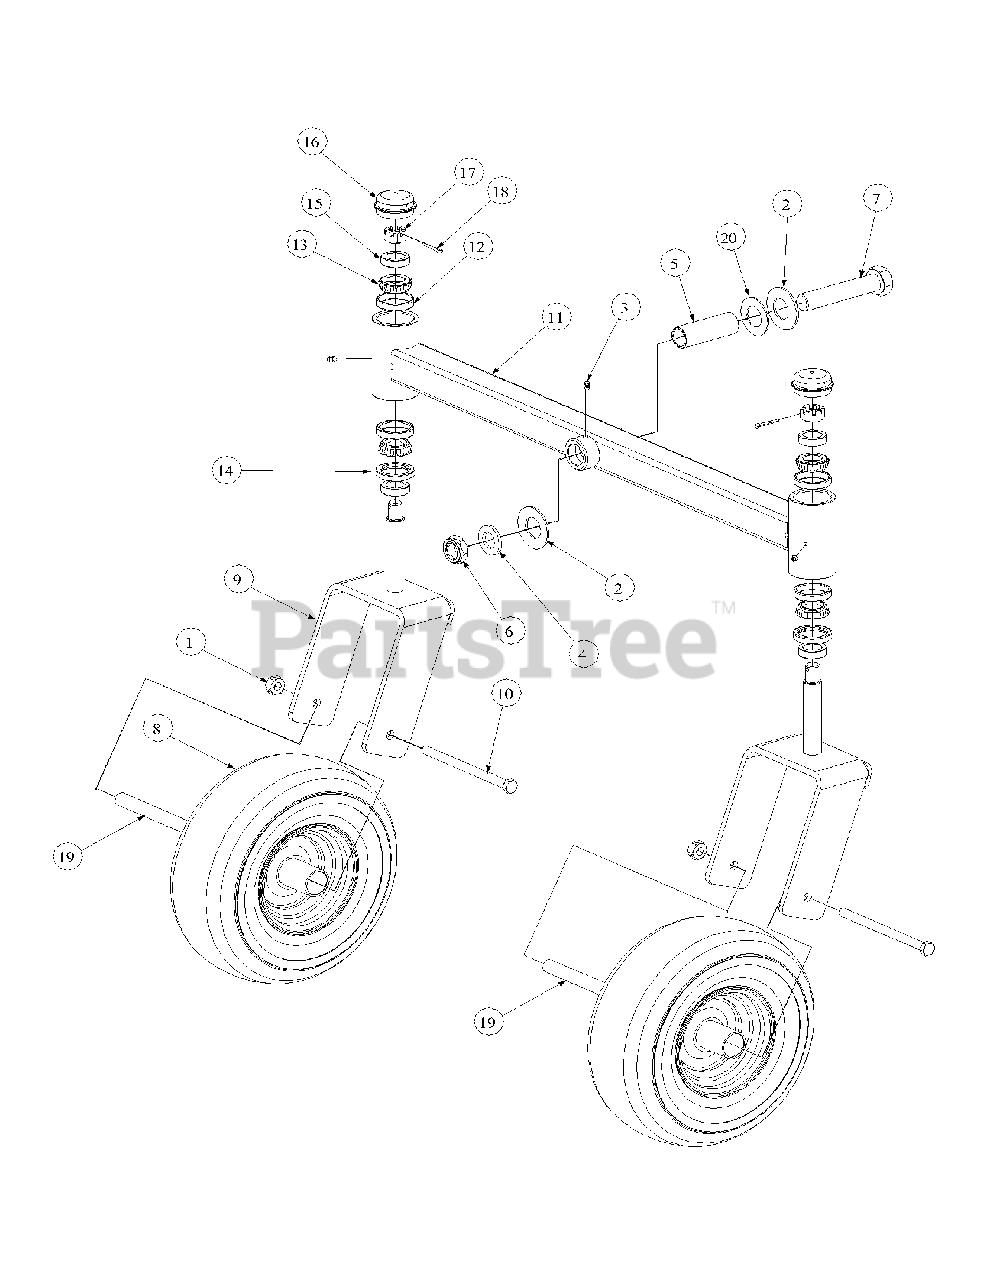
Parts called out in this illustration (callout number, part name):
1	Nut, 1/2-20, Center Lock
2	Bell Washer, 1.25 ID
3	Grease Fitting
4	Special Washer
5	Spacer, 1.005 ID x 1.25 OD x 3.6
6	Nut, Jam, 1.0-14, Insert Lock
7	Hex Cap Screw, 1-14 x 5.0
8	Wheel, 13 x 5-6, White: Includes
8	Front Roller Bearings
8	Front Retainer Bushings
9	Yoke, Caster Wheel
10	HHCS, 1/2-20, 7.00
11	Straight Front Axle
12	Cup Bearing
13	Bearing Cone
14	Seal
15	Ring Seal
16	Grease Cap, 1.986 OD
17	Slotted Nut, 3/4-16
18	Cotter Pin, 5/32, 1.25
19	Wheel Spacer
20	Flat Washer, 1.25 ID
